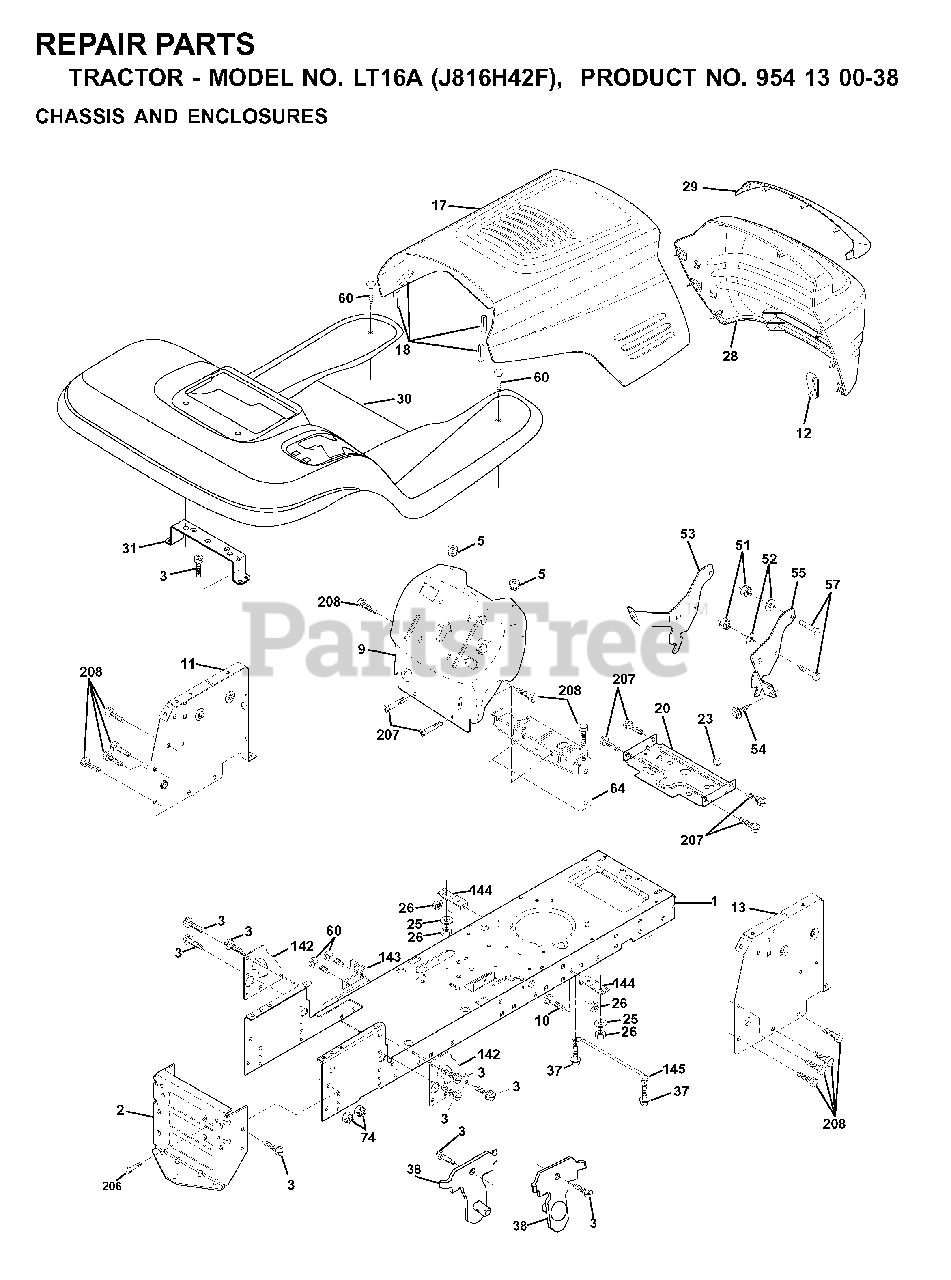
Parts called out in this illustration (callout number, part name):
2	DRAWBAR
3	SCREW 3/8-16X3/4
5	BUMPER.RUBBER.HOOD
10	BOLT D
11	PANEL DASH LH
13	PANEL DASH
18	BUMPER HOOD T
20	PLATE MTG
23	GROMMET T
25	WASHER
26	NUT
38	BRACKET
51	LOCKNUT
57	BOLT
64	DASH LOWER
74	LOCKNUT
142	PLATE
143	BRACKET, SWAY BAR
144	BRACKET FOOTREST
145	ROD PIVOT CHASSIS/HOOD
206	SHOULDER BOLT 5/16-18TT
207	SCREW, 5/16-18 X 1/2
208	SCREW 3/8-16X1/2
